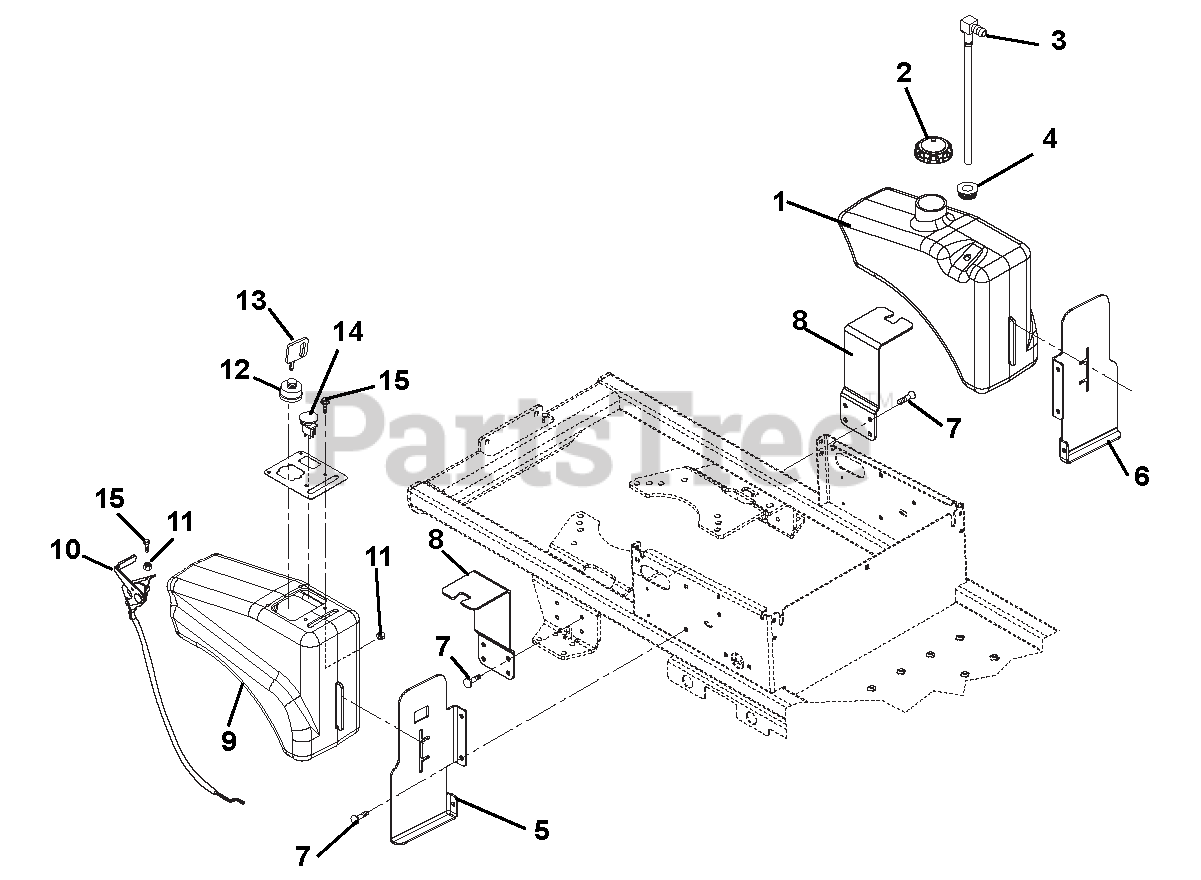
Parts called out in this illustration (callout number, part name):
1	LH FENDER/TANK
2	FUEL CAP
3	FITTING, TANK
4	BSHG-FLG .375 X 1.062 X .625 R
5	BKT, FUEL TANK RH
6	BKT, FUEL TANK LH
7	@SCR-TAP .31-18X.50 HWH TR YWZ
8	MOUNT,FUEL TANK
9	RH FENDER/TANK
10	CABLE,THROTTLE
11	@NUT-LK-NYL 10-24 W/INSRT YWZC
12	KEY SWITCH
13	KEY -W/CAP
14	SWITCH, CLUTCH
15	@SCR-MCH 10-24X.75 HWH YWZC
16	CONTROL PANEL
